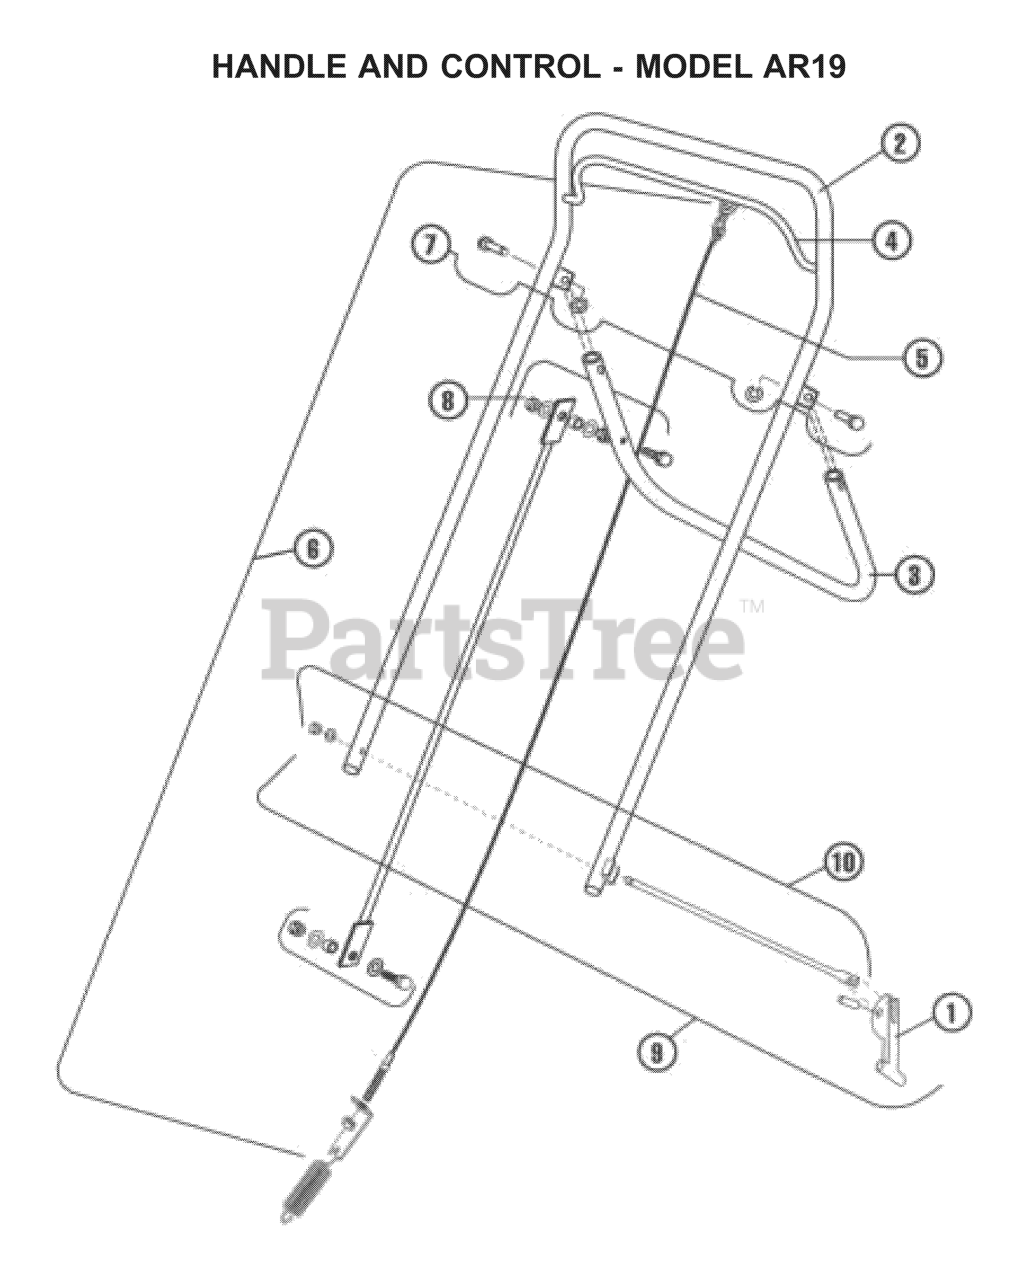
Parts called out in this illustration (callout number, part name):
1	CAM LOCKING LEVER
2	HANDLE
5	CLUTCH CABLE
6	CABLE KIT, CLUTCH
7	PIN KIT, REAR WHEEL
8	CONTROL ROD KIT HV
9	CAM ROD KIT W/O PIVOT SLIDE
10	CAM ROD KIT
